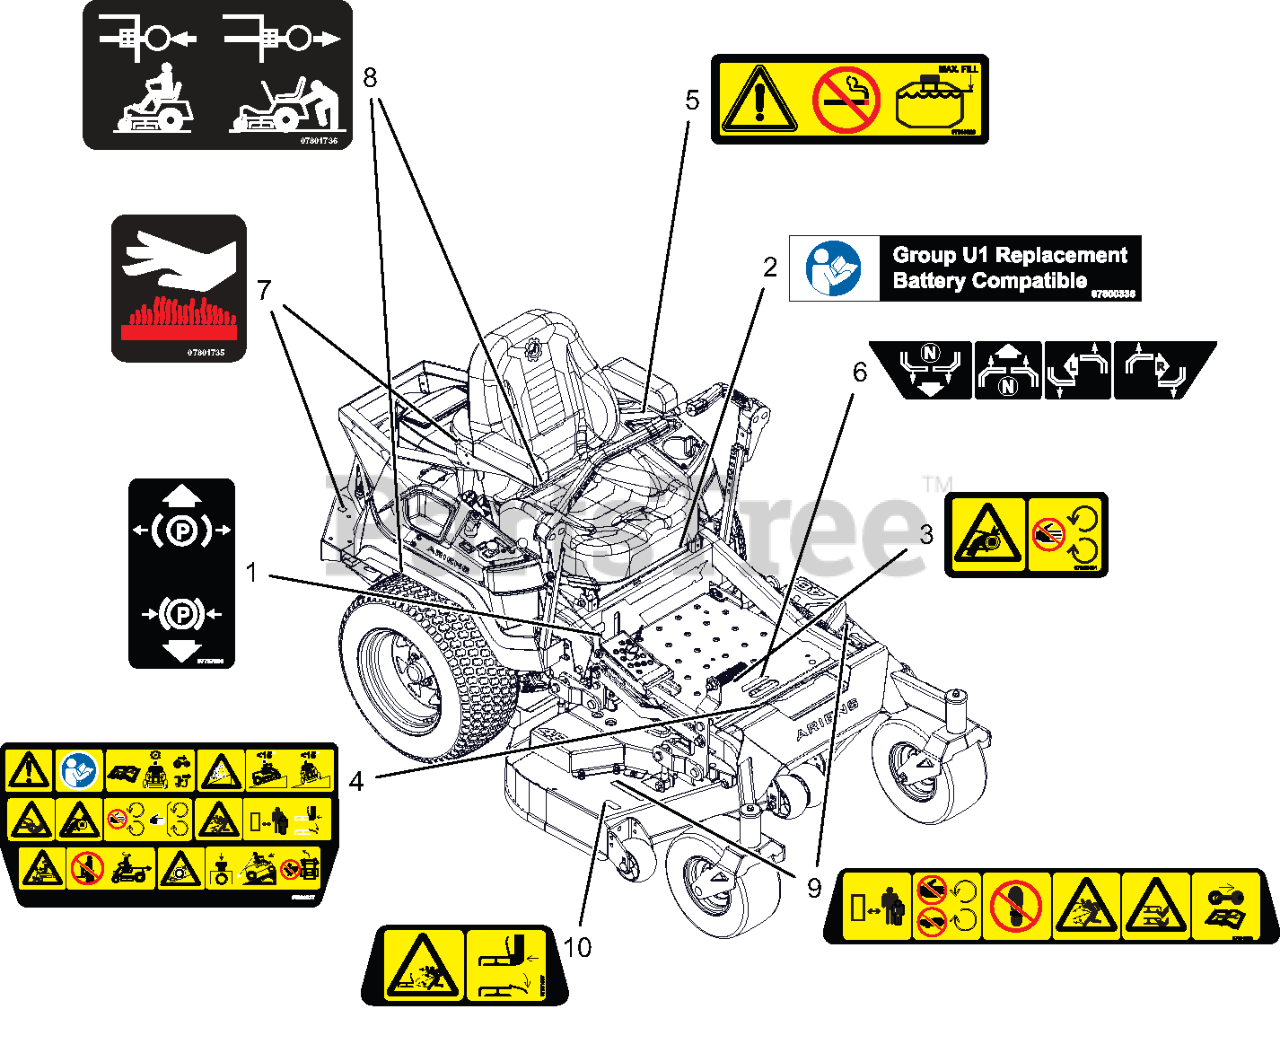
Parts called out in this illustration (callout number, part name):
1	DECAL, PARKING BRAKE LEVER
2	DECAL, U1 BATTERY REPLACEMENT
3	DECAL, SAFETY - GUARDING
4	DECAL, MAIN SAFETY
5	DECAL, FUEL WARNING
6	DECAL, INSTRUCTION - STEERING
7	DECAL- HOT SURFACE
8	DECAL- TRANSAXLE DISCONNECT
9	DECAL- SAFETY - MOWER DECK
10	DECAL- SAFETY - DECK GUARDING
